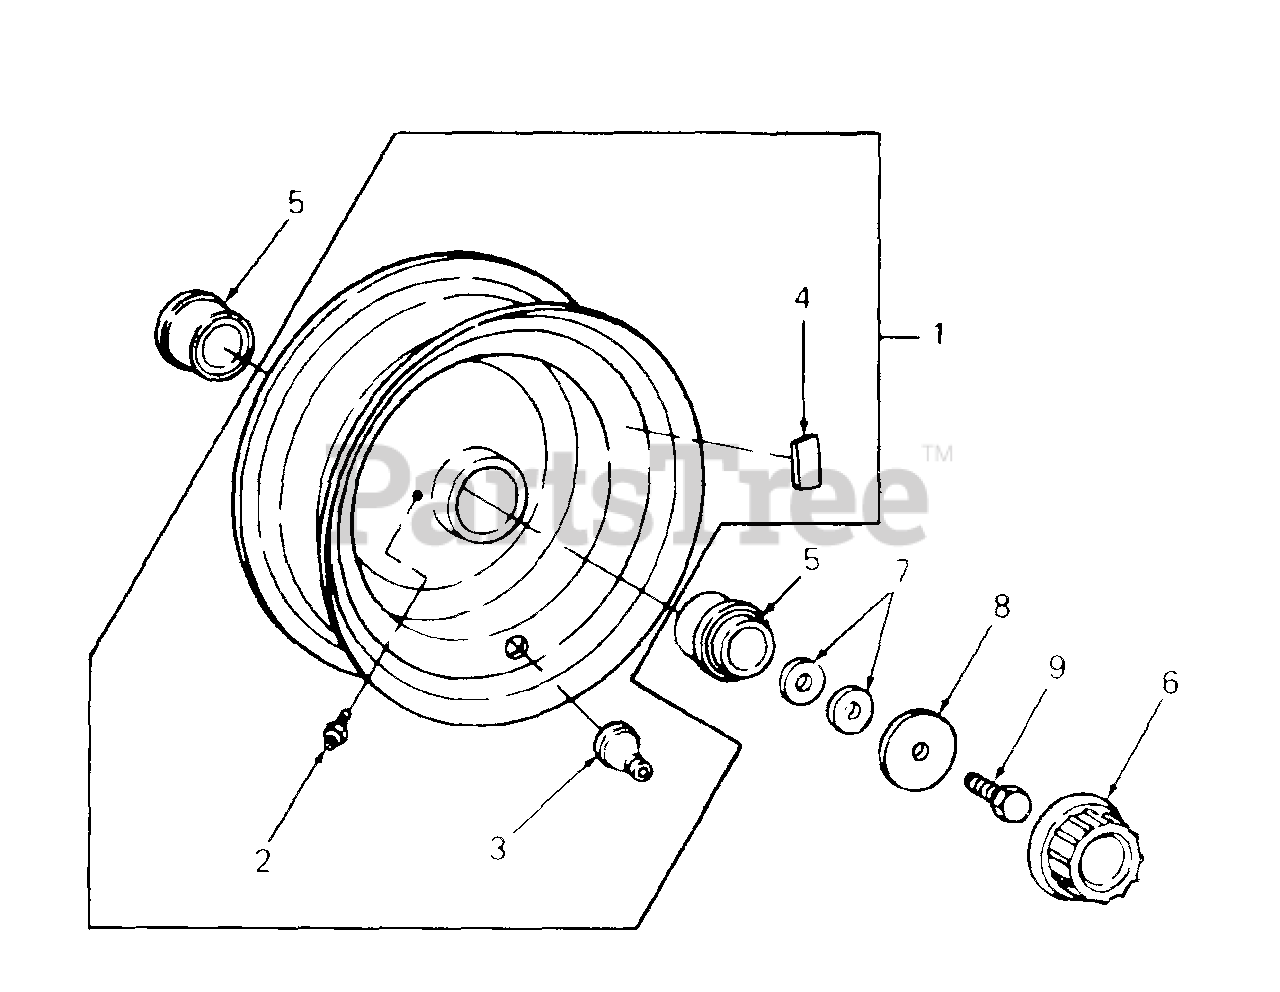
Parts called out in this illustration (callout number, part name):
1	Wheel Assy, Front
2	Fitting, Lube
3	Valve, Tubeless Air
4	Label, Inflation
5	Bearing, Wheel Ball
6	Cap, Hub
7	Washer, Flat, .531 X 1.25 X .100 Thk
8	Washer, Flat, .535 X 1.92 X .060 Thk
9	Bolt, Patch, 1/2-13 X 1.0 Lg GR5
